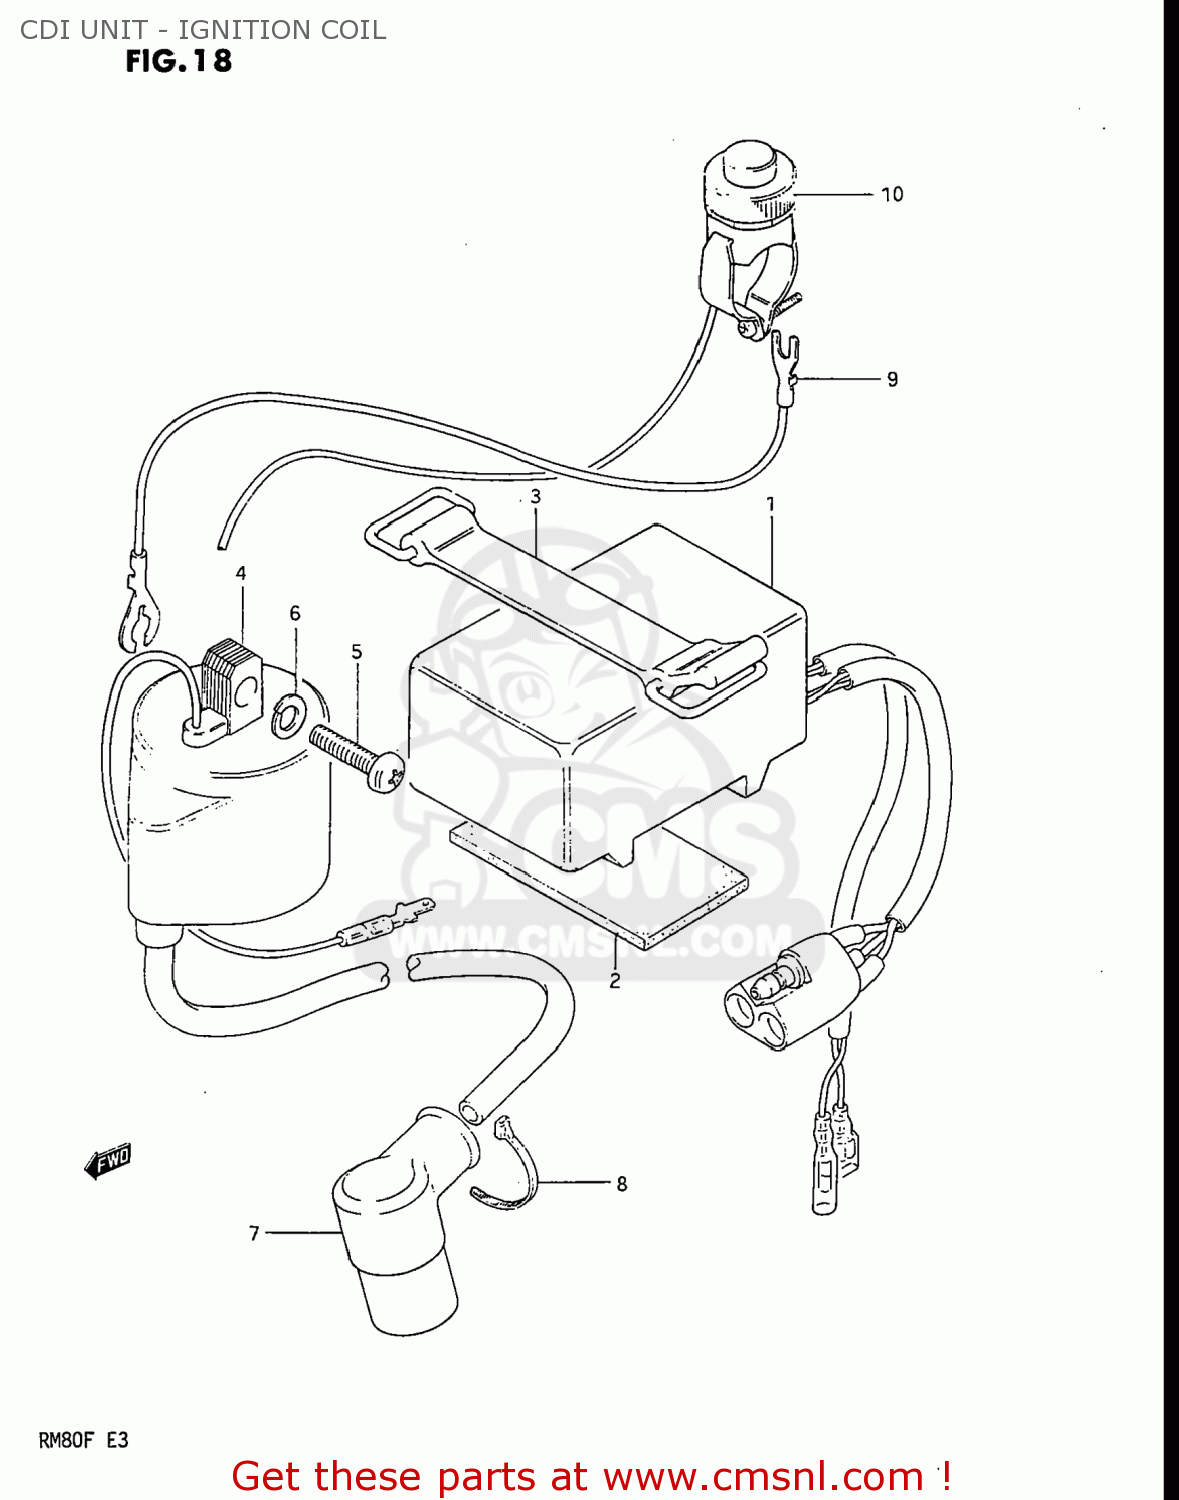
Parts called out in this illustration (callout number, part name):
1	CDI UNIT
2	PROTECTOR,BATTERY
3	BAND
4	COIL ASSEMBLY,IGNITION
5	SCREW
6	LOCK WASHER
7	CAP,SPARK PLUG
8	CLAMP
9	WIRE,ENGINE STOP EARTH
10	SWITCH ASSEMBLY
